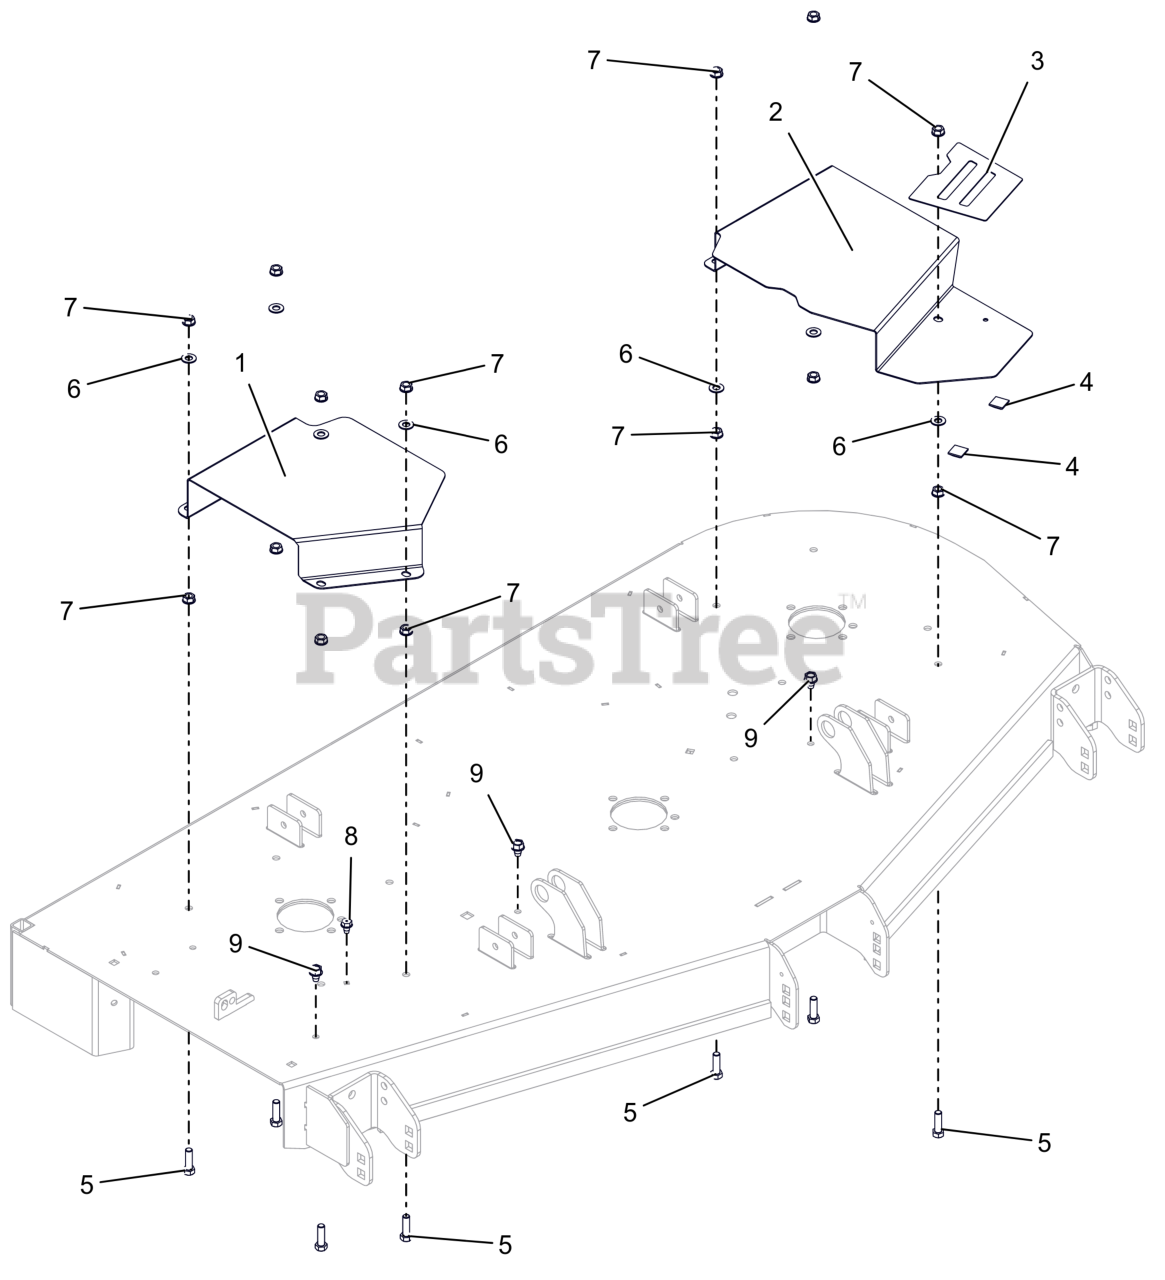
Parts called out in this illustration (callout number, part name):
1	COVER, BELT 52" & 60" RIGHT
2	COVER, BELT 60" LEFT
3	GRIP, TAPE 52-60 BELT COVER
5	BLT, HEX .38-16X1.25 G5 ZCC
6	WSHR,FLT .406X.812X.065 ZCC
7	NUT, SPNLK-FLG .38-16 G5 ZCC
8	SCR,TAP .312-18X.50 HWH TR ZCC
9	SCR,TAP .375-16X.50 HWH TR ZCC
